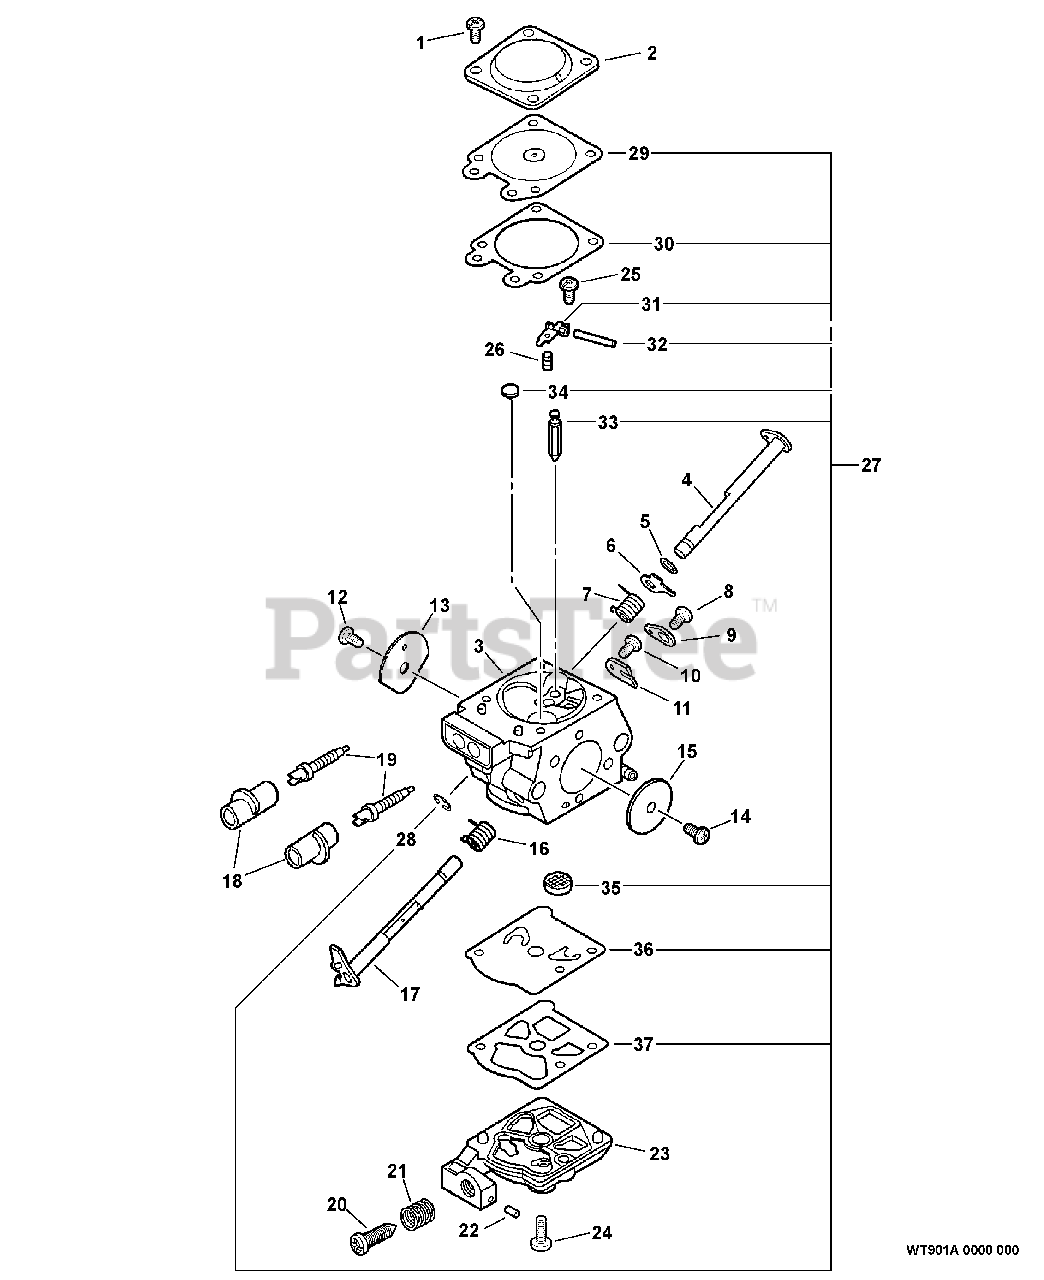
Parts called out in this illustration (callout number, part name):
2	COVER, METERING DIAPHRAGM
3	BODY, CARBURETOR
4	SHAFT, CHOKE
6	LEVER, FAST IDLE
7	SPRING, CHOKE RETURN
9	LEVER, THROTTLE
11	CLIP, THROTTLE SHAFT
13	VALVE, CHOKE
15	VALVE, THROTTLE
16	SPRING, THROTTLE RETURN
17	SHAFT, THROTTLE
18	CAP, LIMITER
19	NEEDLE, MIXTURE
20	SCREW, IDLE ADJUST
21	SPRING, IDLE ADJUST
22	PLUG, FRICTION
23	COVER, FUEL PUMP
25	SCREW, METERING LEVER PIN
26	SPRING, METERING LEVER
27	REPAIR KIT
29	DIAPHRAGM, METERING
30	GASKET, DIAPHRAGM
31	LEVER, METERING
32	PIN, METERING LEVER
33	VALVE, INLET NEEDLE
34	PLUG, WELCH
35	STRAINER
36	DIAPHRAGM, PUMP
37	GASKET, PUMP
